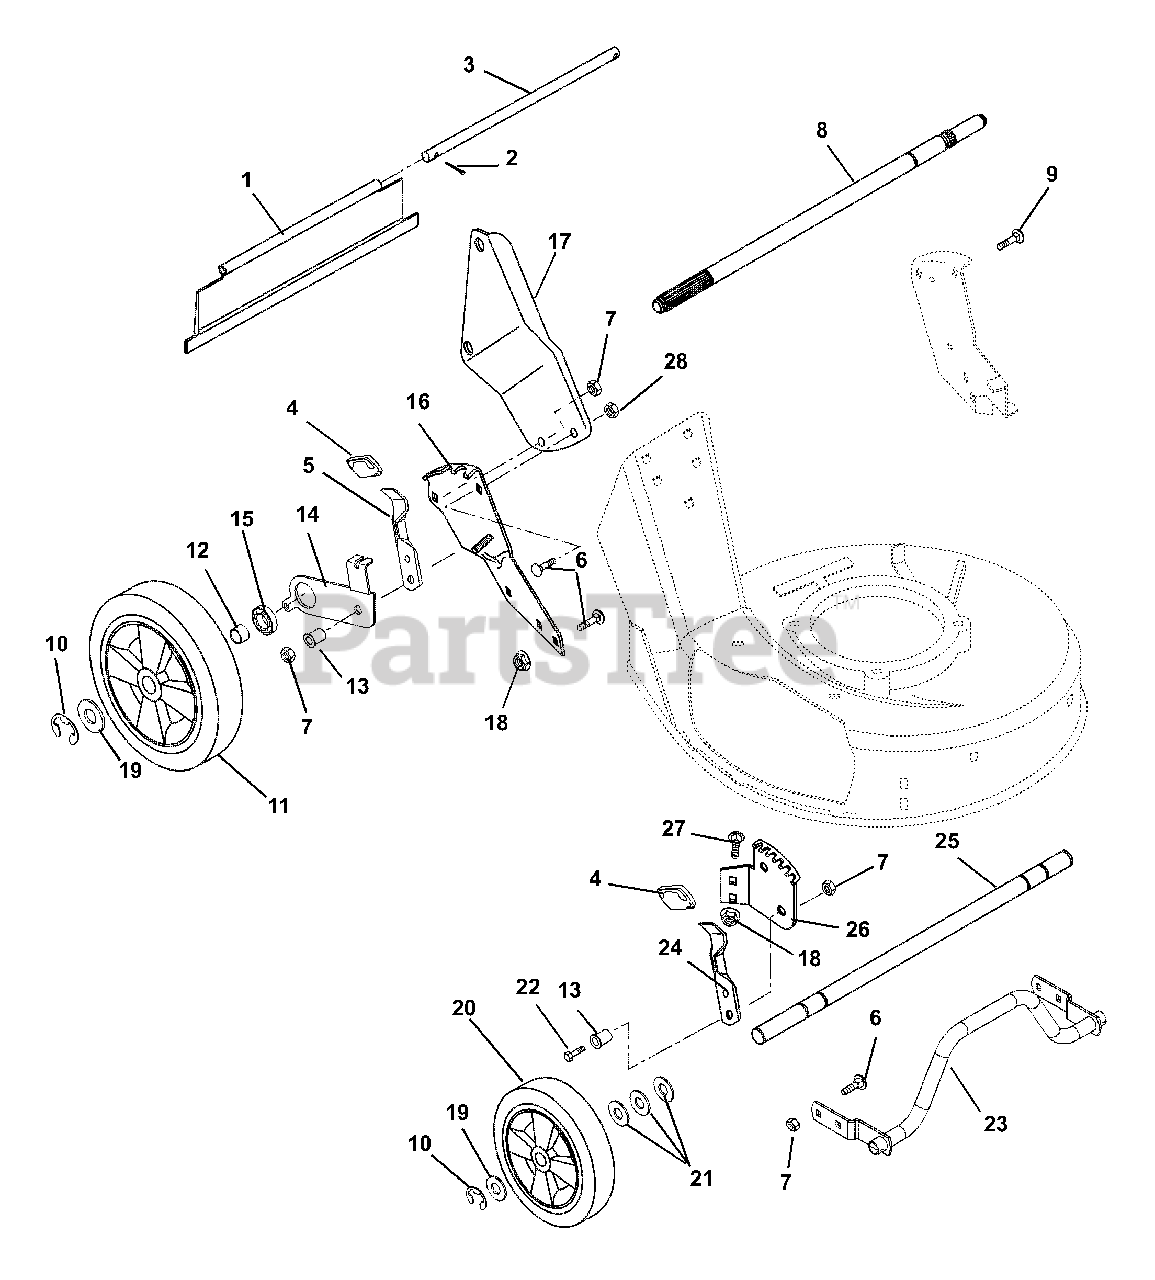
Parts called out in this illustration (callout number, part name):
1	Rear Protective Guard, Self Propelled
1	Rear Protective Guard, Push
2	Pin, Cotter .06 x .50
3	Rod
5	Height Adjustment Lever
6	Bolt, Round Head Square Neck .31-18 x .62
7	Nut, Locking Center .31-18
8	Rear Axle
9	Bolt, Round Head Square Short Neck .31-18 x 1.00
10	Ring, Retaining External .50 x .042
11	Wheel, Left Hand Rear 10.50
11	Wheel, Right Hand Rear 10.50
11	Tire Skin 10.50 x 2.00
11	Tire, Rear 10 x 1.75 #6 Gray
12	Spacer Tube
12	Spacer Tube Push Left Hand
12	Spacer Tube Push Right Hand
13	Bushing, Flange .312 x .50 x .344 x .88
14	Rear Adjustment Bracket Left Hand
14	Rear Adjustment Bracket Right Hand
14	Rear Bracket and Bearing Assembly Left Hand
14	Rear Bracket and Bearing Assembly Right Hand
14	REAR BRACKET AND BEARING ASSY RH
15	Bearing, Ball .625 x 1.38 x .50
16	Rear Quadrant, Left Hand
16	Rear Quadrant, Right Hand
17	Bracket, Handlebar Mounting-Right Hand
17	Bracket, Handlebar Mounting-Left Hand
18	Nut, Locking Flange .31-18
19	Washer, Flat Steel .505 x .88 x .072
20	Wheel 7.50-.50 Bore, 1.50 Hub
20	Tire, Front 7.00 x 1.50 #6 Gray
21	Washer, Flat Steel .520 x .827 x .062
22	Bolt, Hex .31-18 x 1.00 Grade 5
23	Guard, LM Valve Cover
24	Lever, Front Height Adjustment
25	Front Axle
26	Front Quadrant, Left Hand
26	Front Quadrant, Right Hand
27	Bolt, Round Head Square Neck .31-18 x .50 Grade 5
28	Nut, Locking Nylon .31-18
